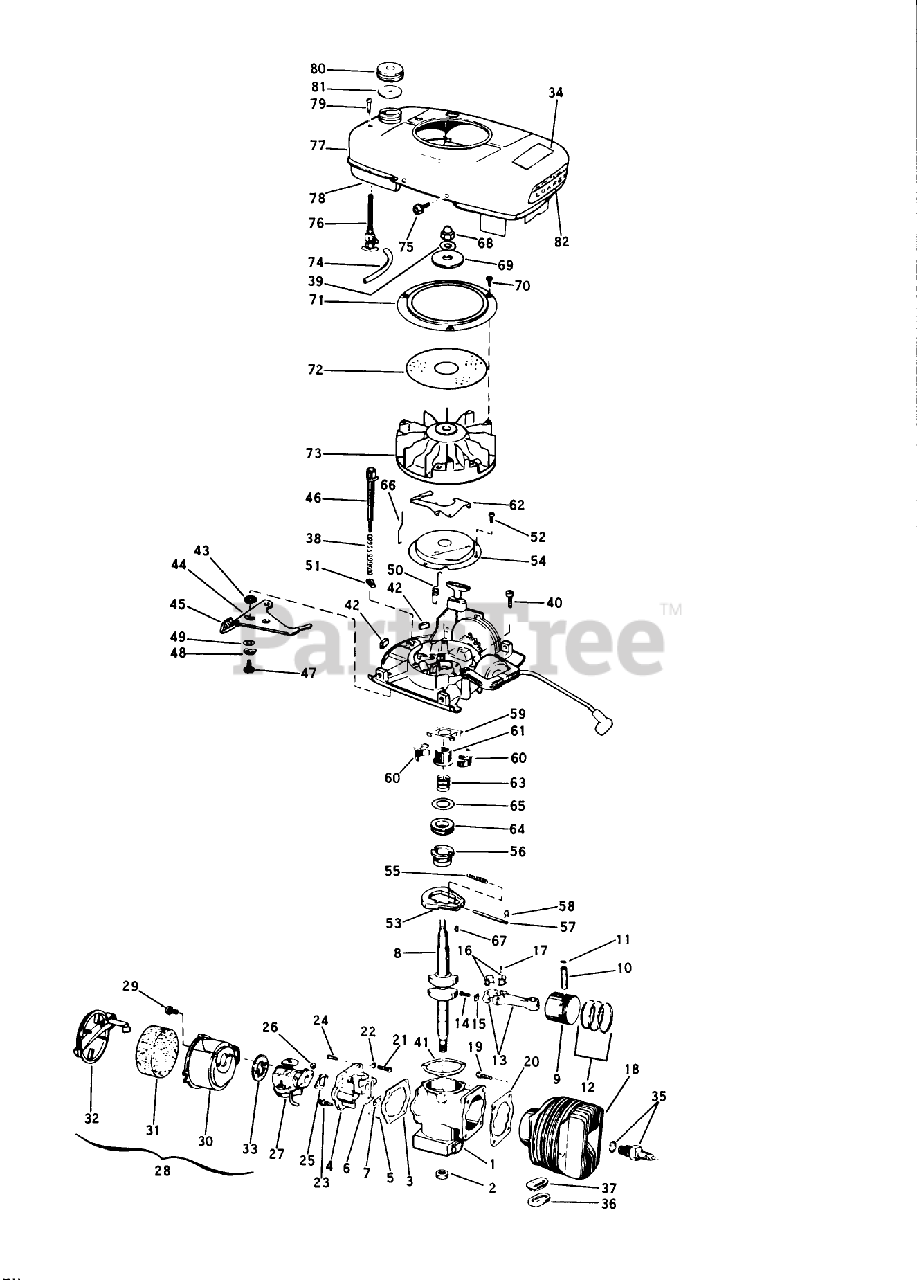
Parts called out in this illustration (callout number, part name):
7	PLATE-BACKUP, REED
11	RING-RETAINING
16	LINER ASM
20	GASKET S
23	SCREW S
24	SCREW S
25	GASKET S
26	STOP NUT
29	SCREW S
31	AIR FIL.ELEM S
34	Decal-Instruction
35	Spark Plug
36	GASKET S
38	SPRING S
41	GASKET S
43	Washer-Vari-Speed
52	SCREW S
53	FLYWEIGHT S
54	DUST COVER S
55	SPARK ADV. SPRING S
56	SPARK ADV. S
57	PIN,SPARK ADV. S
58	SPARK ADJ. SPRING
61	COLLAR S
62	LEVER-GOVERNOR S
63	SPRING S
64	THRUST COLLAR S
71	Ring-Flywhl. Scrn.
75	SCREW S
76	VALVE&SCREEN SM
